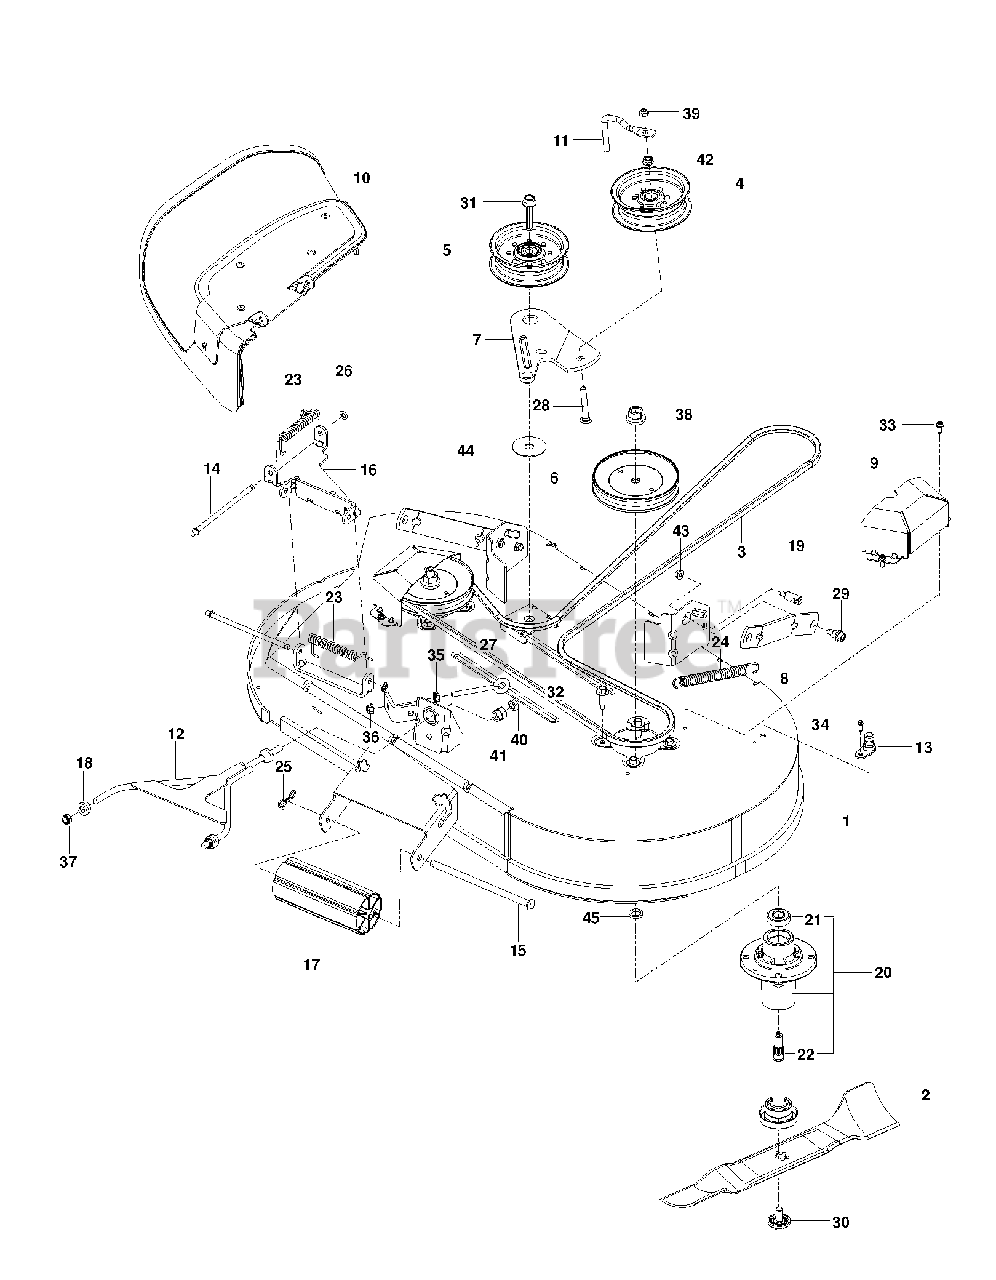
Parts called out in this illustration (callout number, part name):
1	HOUSING.ASM.PNT.42.WELL.ZTR
2	BLADE.42.FCS.BAGGING.BLADE.RAW
3	BELT.42.FCS.ZTR.DECK.DRIVE
4	PULLEY.IDLER.2006
5	PULLEY.IDLER.MWR.STATI.LH
6	PULLEY MANDREL 5.0"
7	ARM.42"FCS.CLUTCHING.X431
8	ARM.RFIXED.MOWER.SUSPNSIONX431
9	COVER.42".MANDREL.FCS X668
10	DEFLECTOR.ASM.42.FCS.ORANGE
11	KEEPER.BELT.IDLER.54"T
12	LINK.FRONT.WLDMNT.RZ X431
13	PORT.WASHOUT
14	ROD.HINGE
15	ROD.ROLLER.NOSE.NARROW.48"
16	BRACKET.42".FCS.DBLE.HINGEX668
17	NOSE ROLLER 48"
18	BUSHING SPHERICAL SUSP. FRONT
19	STUD.FASTNER.W/ANTI-ROTATE
20	MANDREL.DECK.ASSEMBLY
22	SHAFT ASM MANDREL
23	SPRING.42.FCS.DEFLECTOR
24	SPRING.MOWER.DRIVE.ELECTRIC
25	PIN.COTTER.5/16.BOW TI
26	NUT PUSH M
27	EYE BOLT 5/16 X 3.50
28	BOLT
29	BOLT.SHOULDER
30	BOLT.WASHER.ASM.7/16-2
31	SCREW.7/16-14X2.125.HEX.WSH.HD
32	SCREW, WASHER HEAD
33	SCREW.1/4-20X5/8
34	SCREW.TT.#10-32X.5.3/8.FLANGE
35	NUT 5/16C WHIZ
36	5/16-18 NYLOC FLANGE NUT
37	NUT, 7/16-20 HEX NYLOC ZC
38	NUT.FLANGE.LOCK.TOP
40	NUT.ASF.HEX.7/16
41	NUT, LIFT LINK 7/16-20
42	HEX FLANGE LOCKNT
43	NUT LOCK HEX FLANGE 5/16-18
45	WASHER.SPACER.MANDREL
